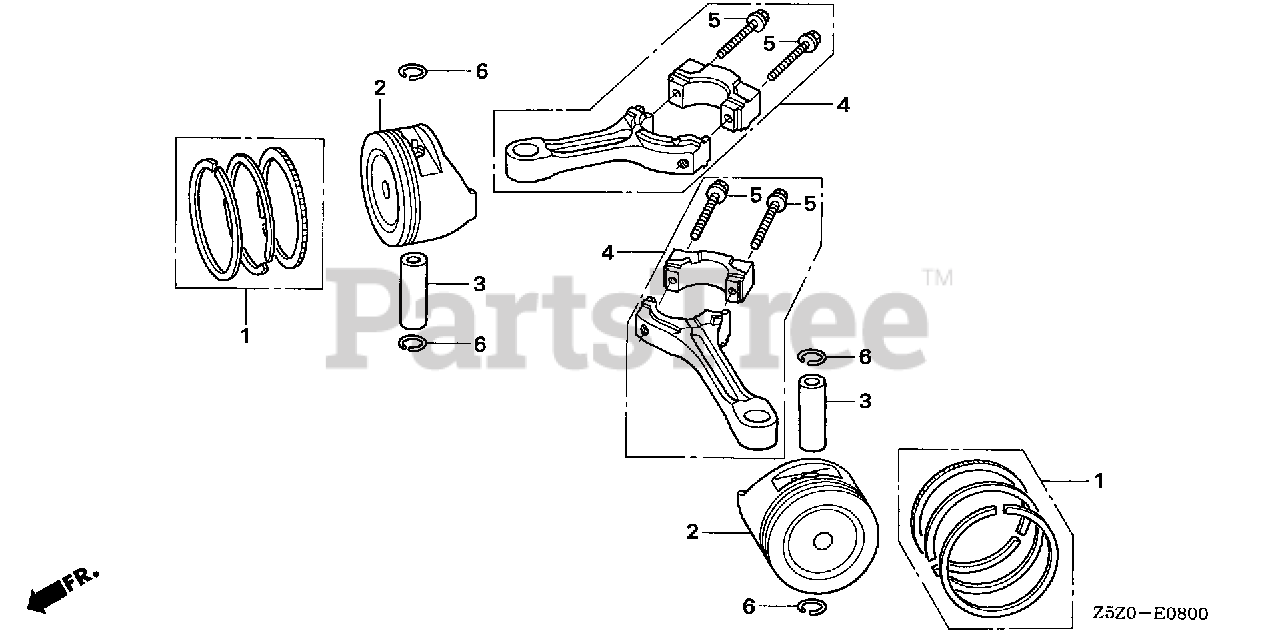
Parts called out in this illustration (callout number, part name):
1	RING SET, PISTON (STD) (NIPPON)
1	RING SET, PISTON (STD) (TEIKOKU)
2	PISTON (STD)
3	PIN, PISTON
4	ROD ASSY., CONNECTING
5	BOLT, CONNECTING ROD (6X37)
6	CLIP, PISTON PIN (18MM)
